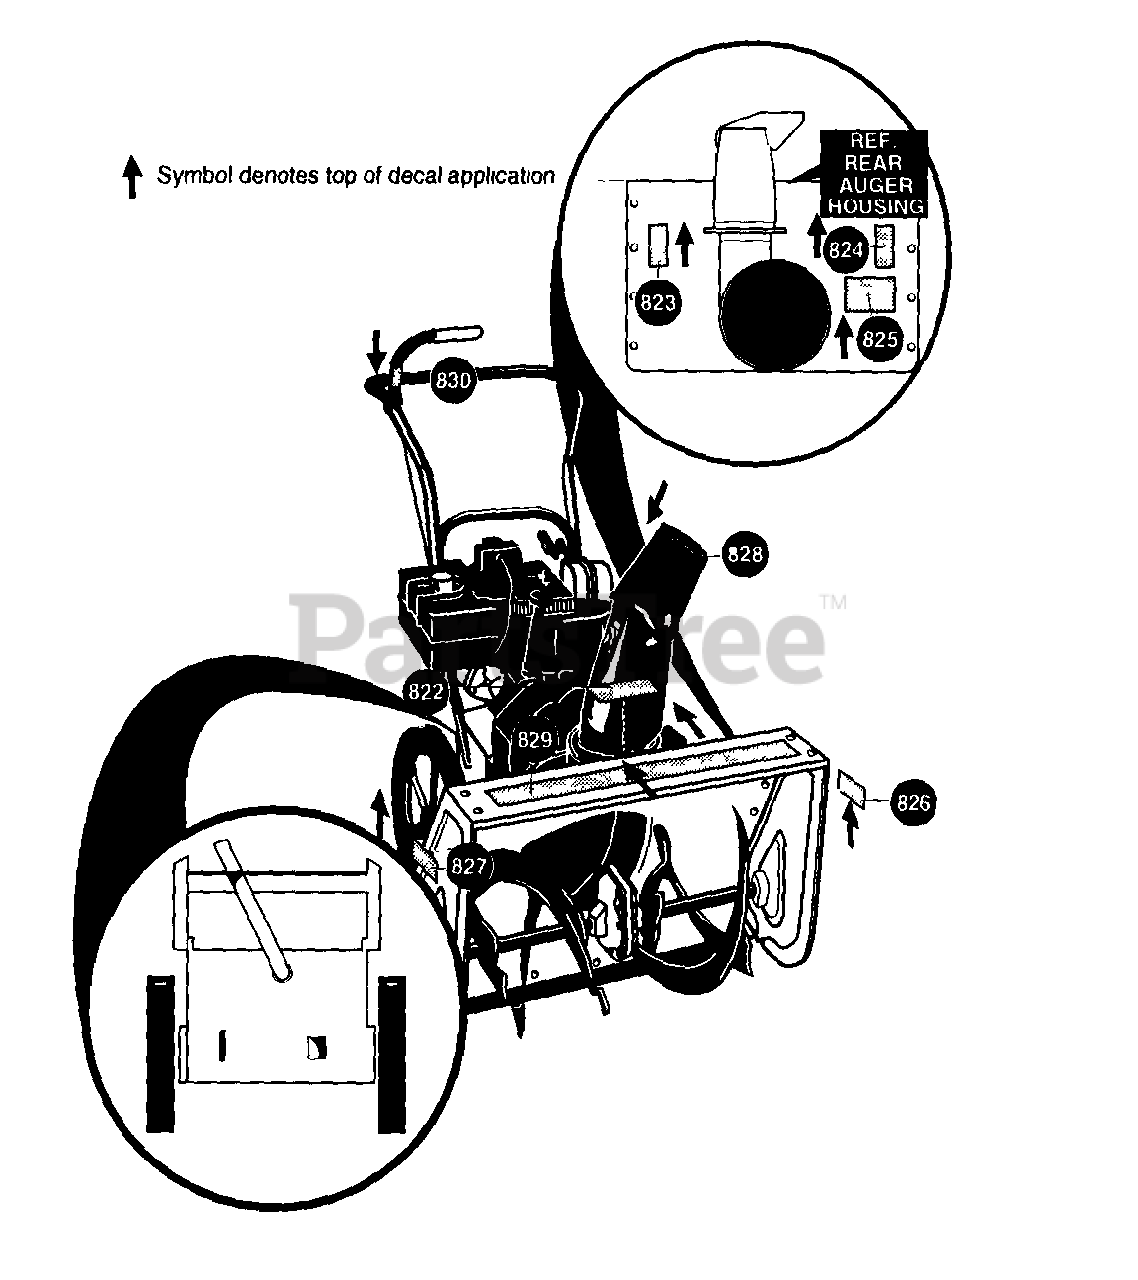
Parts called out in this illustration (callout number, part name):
822	Decal, 9" Impeller
823	Decal, Danger Auger E/F
824	Decal, Danger Chute E/F
825	Decal, Safety Inst E/F
828	Decal, Danger Chute
829	Decal ST522H Top Cover
830	Decal, Auger Dr Engage
